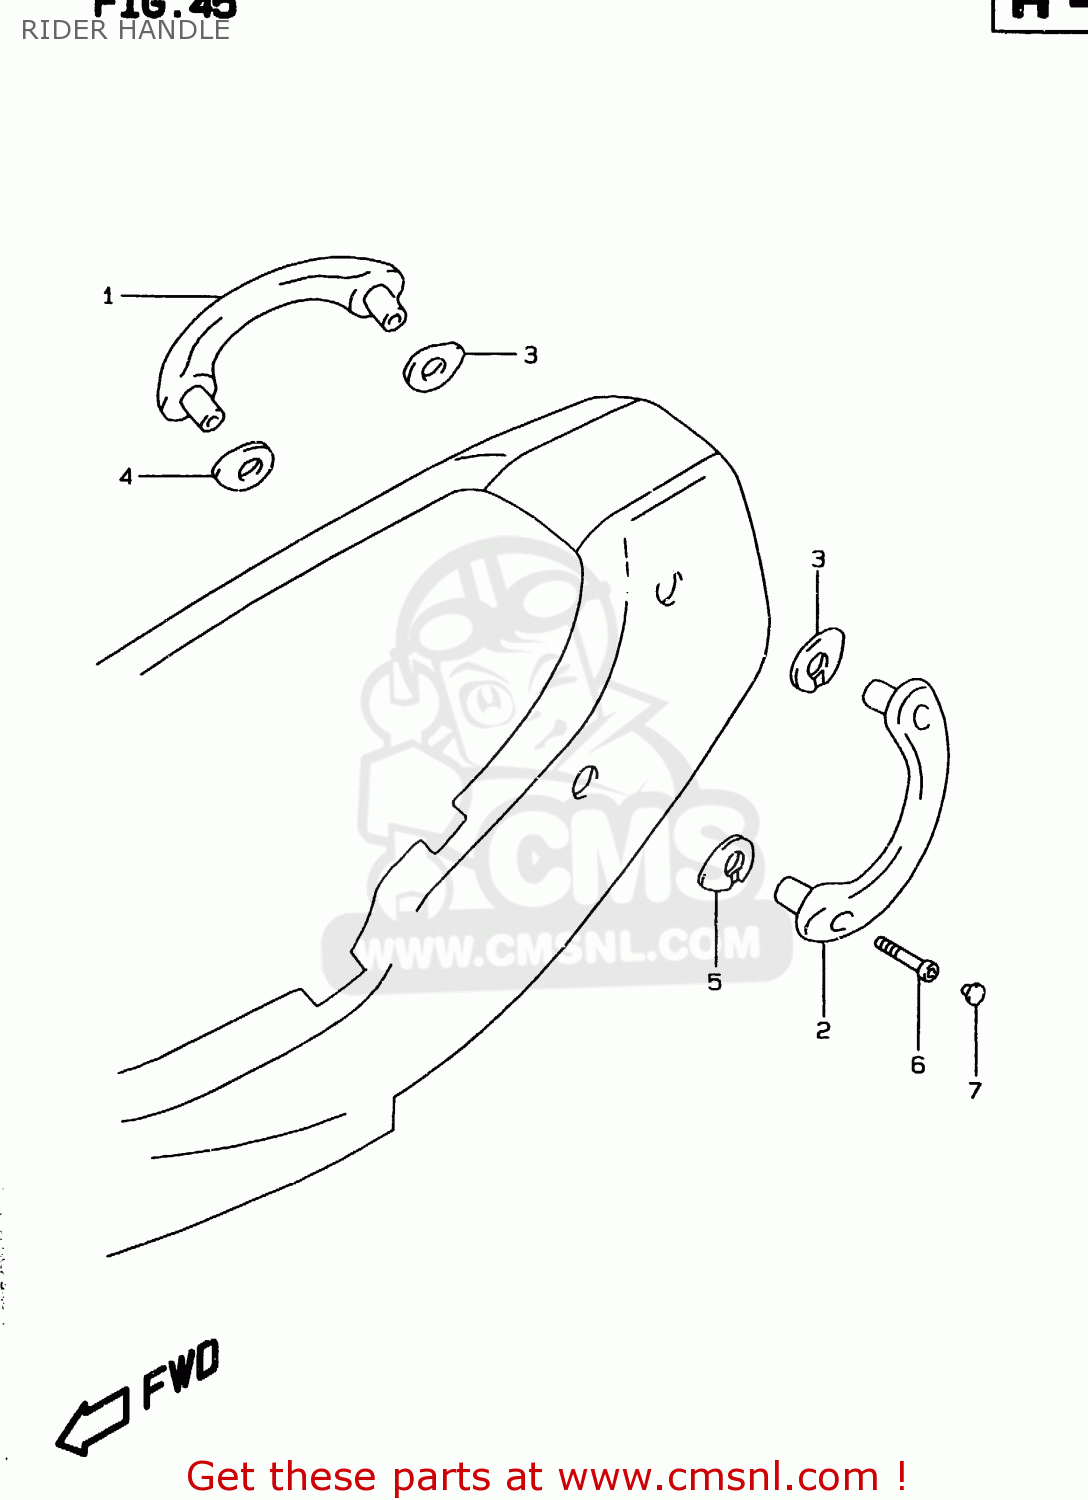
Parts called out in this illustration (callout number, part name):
1	HANDLE,PILLION RIDER,R
2	HANDLE,PILLION RIDER,L
3	CUSHION,PILLION HANDLE UPR
4	CUSHION,PILLION HANDLE LWR,R
5	CUSHION,PILLION HANDLE LWR,L
6	BOLT
7	CAP(OD:14.5)
